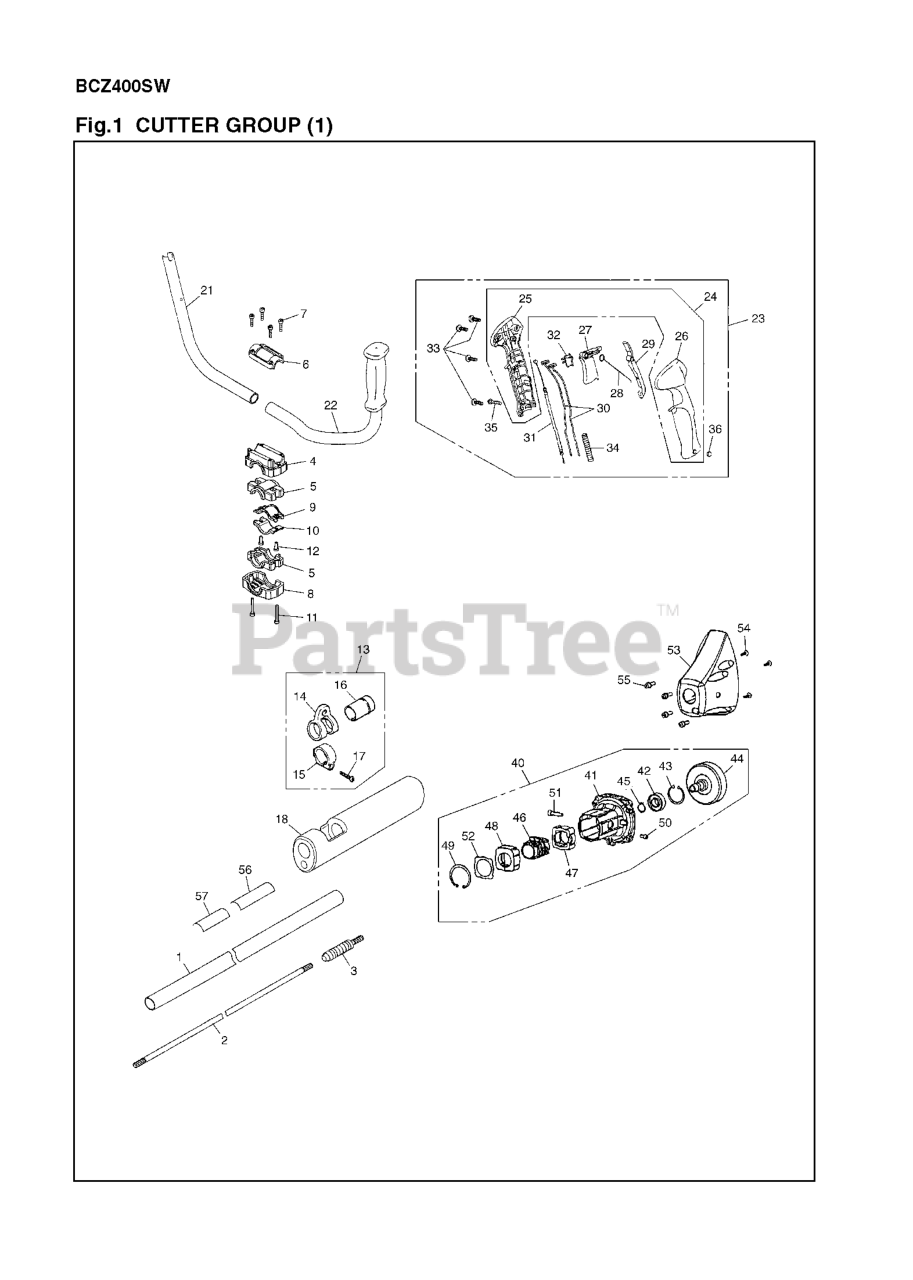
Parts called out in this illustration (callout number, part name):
1	PIPE ASSY
2	SHAFT, SPLINE
3	JOINT ASSY
5	ABSORBER
6	BRACKET-UP
7	BOLT TORX
9	CLAMP(A)
10	CLAMP(B)
11	BOLT TORX M5XL35
13	HANGER ASSY
18	PROTECTOR
21	HANDLE, (R)
22	HANDLE, (L)
23	GRIP ASSY
24	HANDLE COMPLETE
25	BODY-R
26	BODY-L
30	CORD COMP
31	CABLE ASSY
40	HOUSING ASSY
42	BEARING 0600406202
43	SNAP RING
44	DRUM
45	RING, SNAP, M15 x 1.0
47	ABSORBER
48	ABSORBER
56	PLATE,NAME
57	LABEL CAUTON FOR BC
